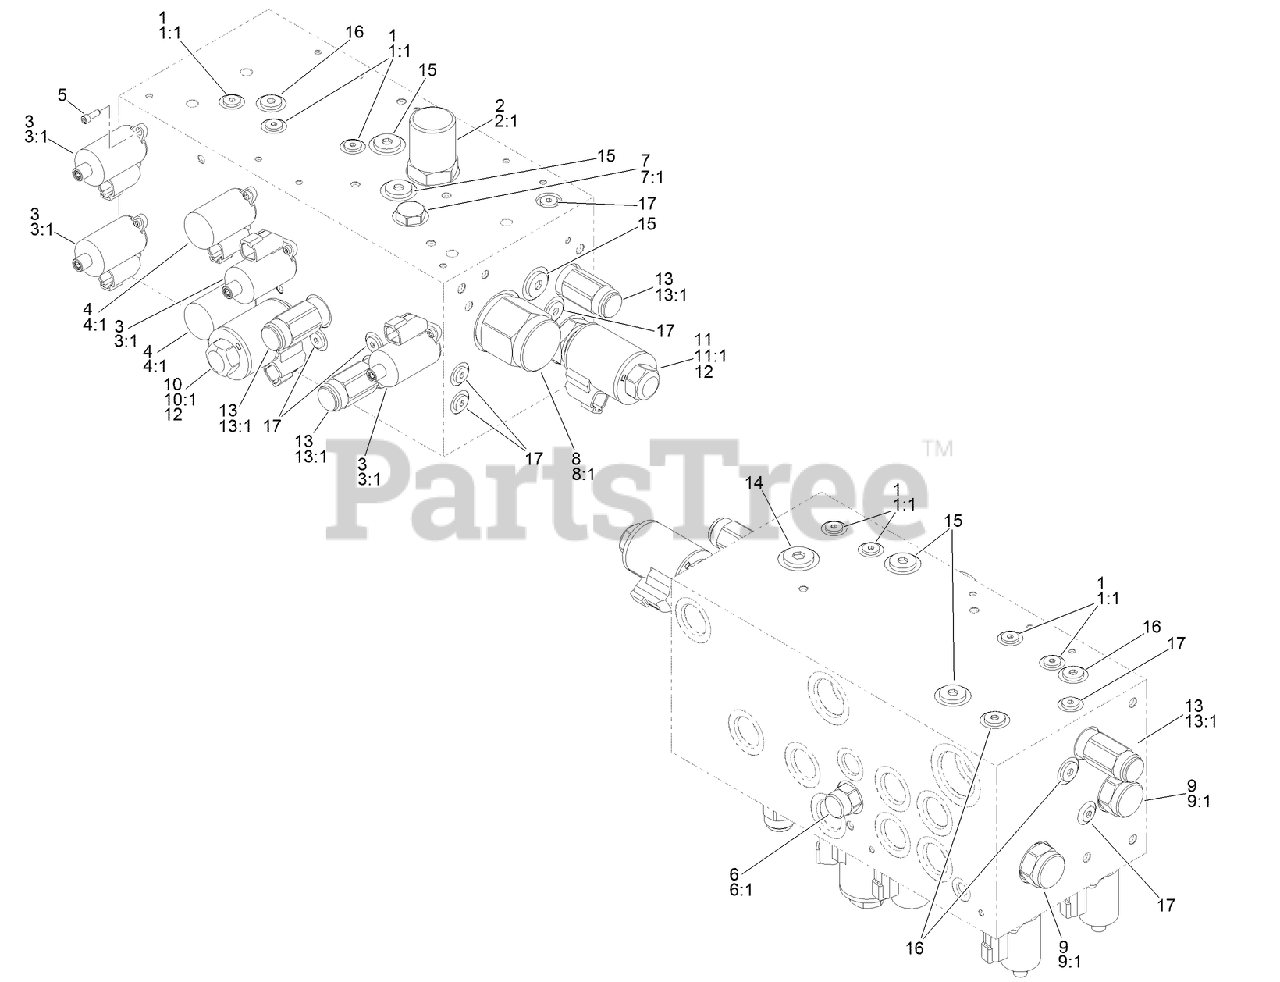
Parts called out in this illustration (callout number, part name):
1	VALVE-CHECK
1:1	SEAL KIT
2	REGULATOR-FLOW
2:1	SEAL KIT
3	VALVE-PROPORTIONAL
3:1	SEAL KIT
4	VALVE-PROPORTIONAL
4:1	SEAL KIT
5	SCREW-SHCS
6	REGULATOR-FLOW
6:1	SEAL KIT
7	SHUTTLE-LOAD
7:1	SEAL KIT
8	VALVE-PILOT
8:1	SEAL KIT
9	VALVE-PILOT
9:1	SEAL KIT
10	VALVE-PROPORTIONAL
10:1	SEAL KIT
11	VALVE-PROPORTIONAL
11:1	SEAL KIT
12	COIL-VALVE
13	VALVE-RELIEF
13:1	SEAL KIT
14	PLUG-PORT
15	PLUG-PORT
16	PLUG-HYD, SAE
17	PLUG-PORT
